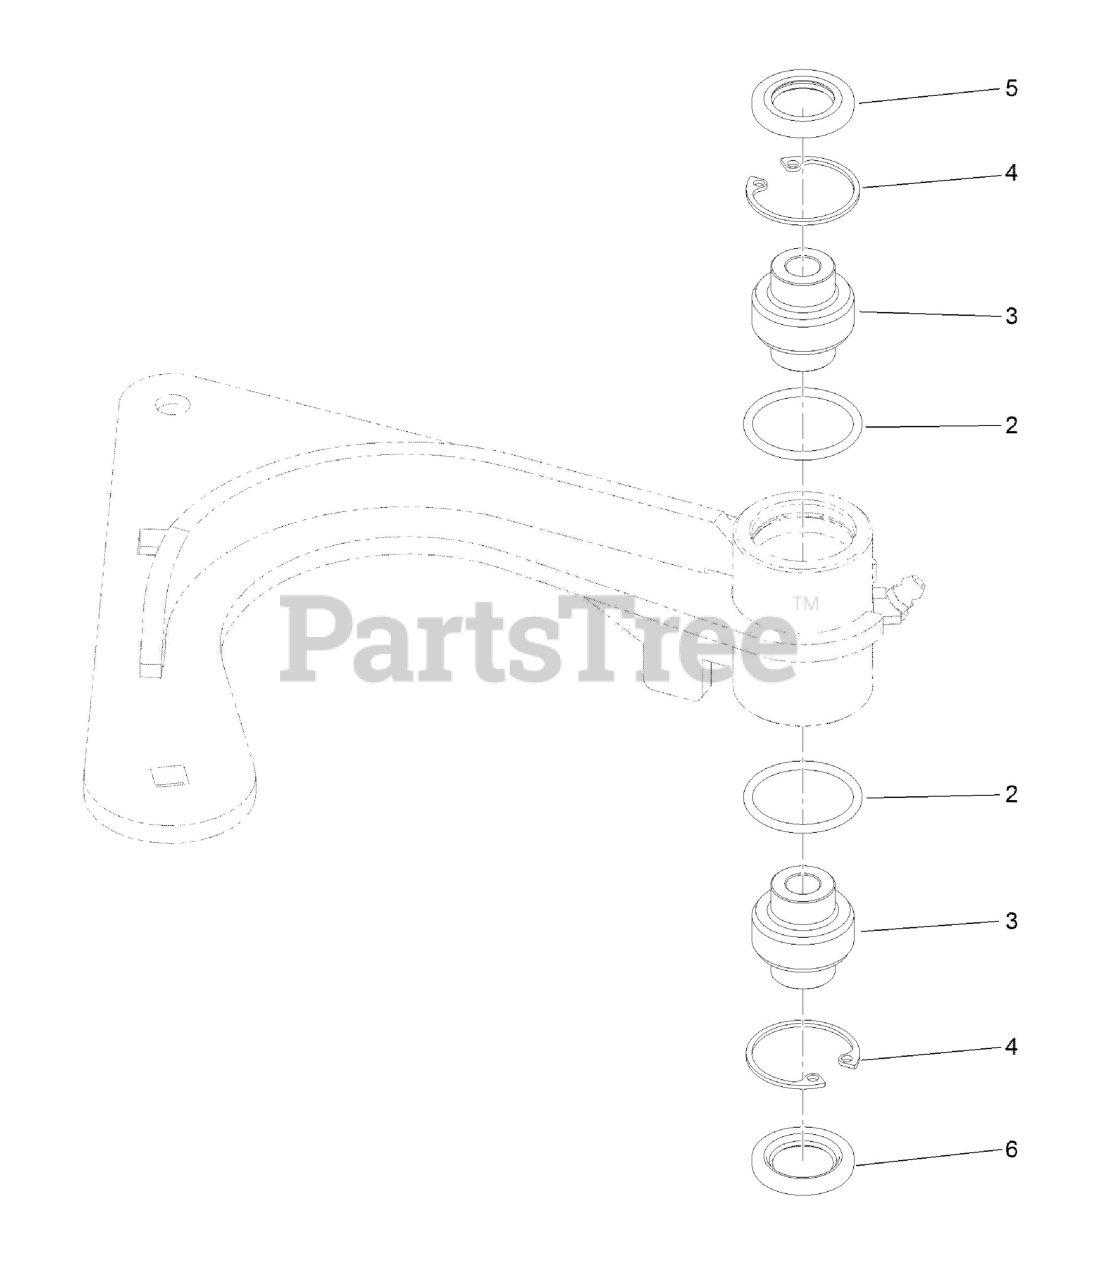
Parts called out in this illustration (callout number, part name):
3	BEARING-SPHERICAL
4	RING-SNAP
5	SEAL-LIP, DOUBLE
6	SEAL-LIP, SINGLE
